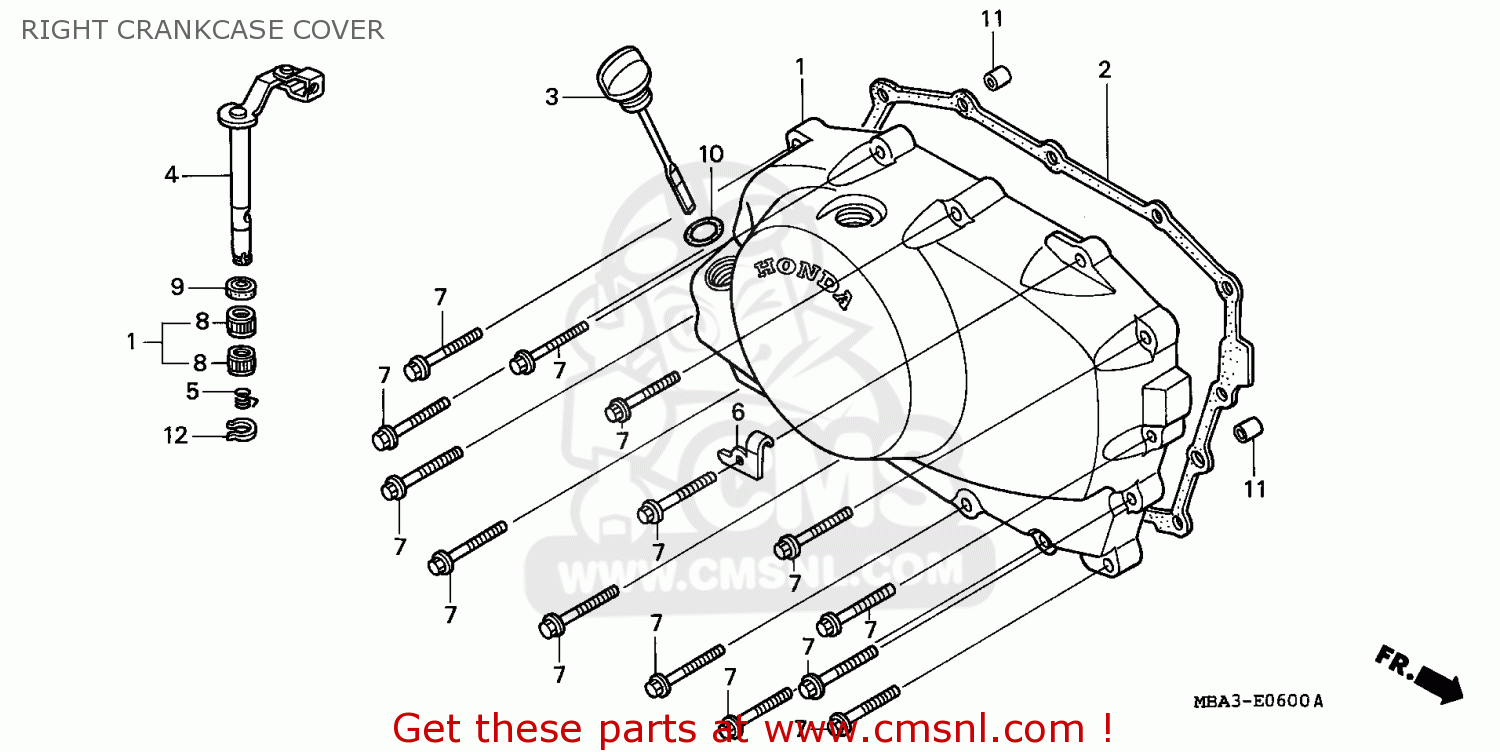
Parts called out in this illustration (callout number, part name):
1	COVER COMP,R CRAN
2	GASKET,R.COVER (NAS)
3	GAUGE COMP,OIL LE
4	LEVER COMP.,CLUTC
5	SPRING,CLCH.LEVER
6	RECEIVER,CLUTCH W
7	BOLT,FLANGE,NSHF,
8	NEEDLE BRG
9	OIL SEAL 12X18X5
10	O RING,21.5M/M
12	CIRCLIP, 10M/M
